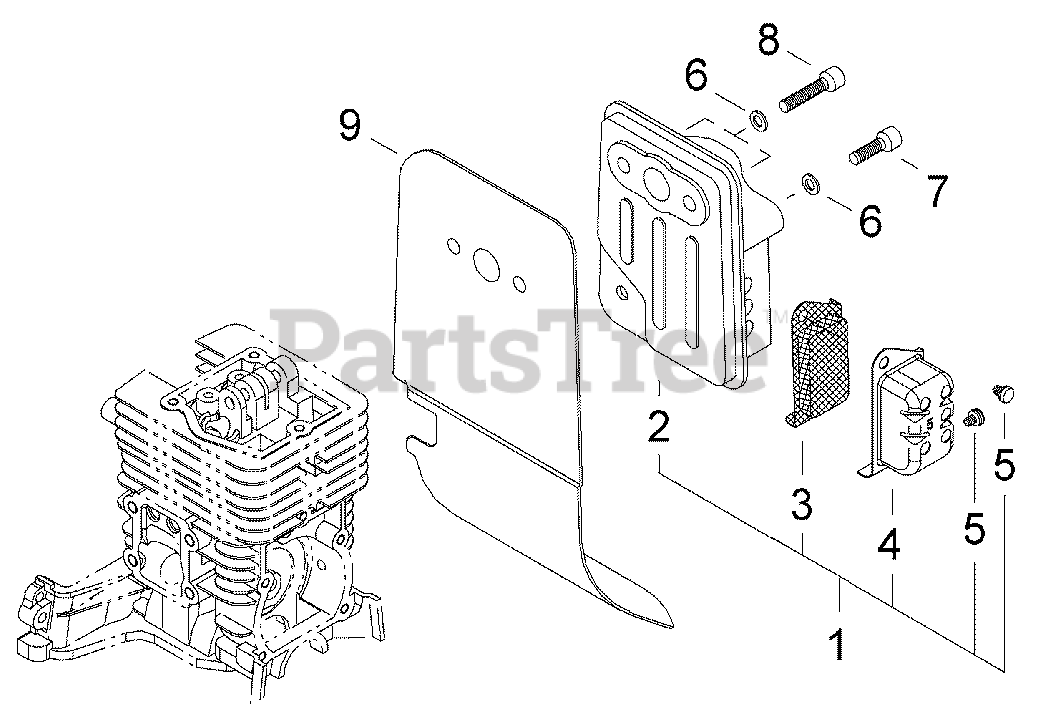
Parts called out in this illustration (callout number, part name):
1	MUFFLER ASSY
2	MUFFLER
3	SCREEN, SPARK ARRESTOR
4	GUIDE, EXHAUST
5	SCREW - 4X6
6	WASHER - 5
7	SCREW - 5X16
8	SCREW - 5X25
9	SHIELD, EXHAUST
